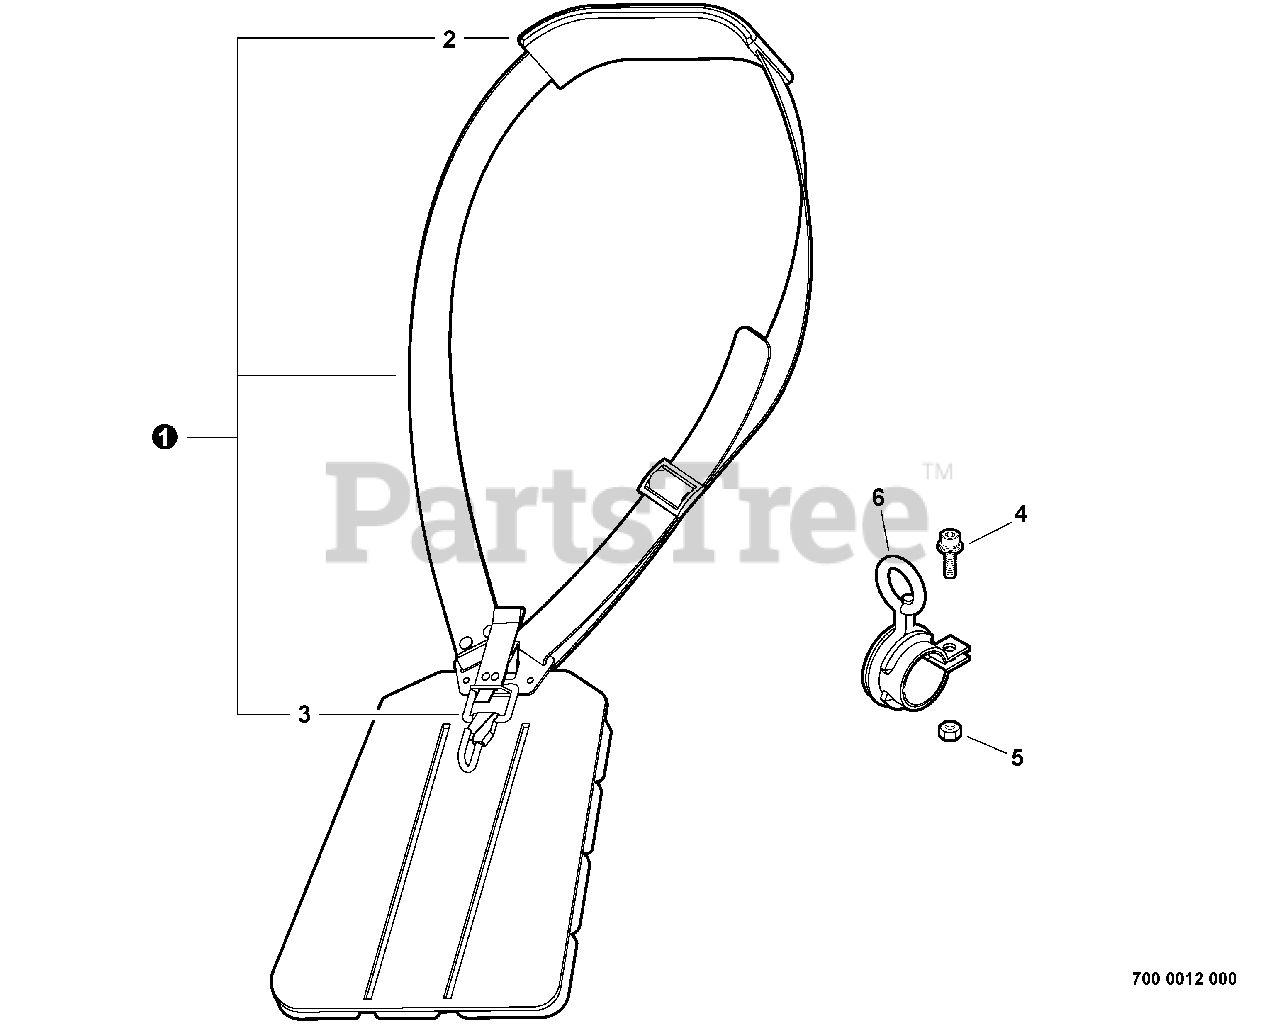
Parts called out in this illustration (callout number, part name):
1	HARNESS ASSY, BRUSHCUTTER
2	PAD, SHOULDER
3	HOOK, SNAP
4	BOLT M5×12
5	NUT M5
6	HANGER, SWIVEL
